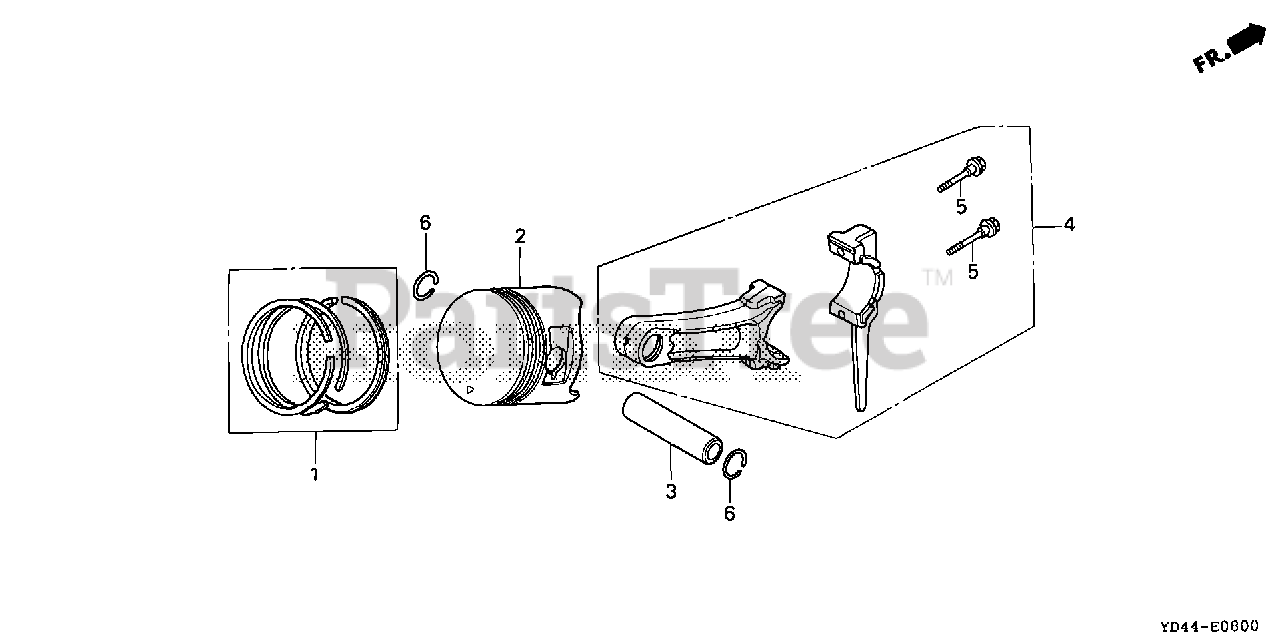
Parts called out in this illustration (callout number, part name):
1	RING SET, PISTON (STD) (NIPPON)
1	RING SET, PISTON (0.25) (NIPPON)
1	RING SET, PISTON (0.50) (NIPPON)
1	RING SET, PISTON (0.75) (NIPPON)
2	PISTON (STD)
2	PISTON (0.25)
2	PISTON (0.50)
2	PISTON (0.75)
3	PIN, PISTON
4	ROD ASSY., CONNECTING (STD)
4	ROD ASSY., CONNECTING (0.25 LOWER SIZE)
5	BOLT, CONNECTING ROD
6	CLIP, PISTON PIN (20MM)
